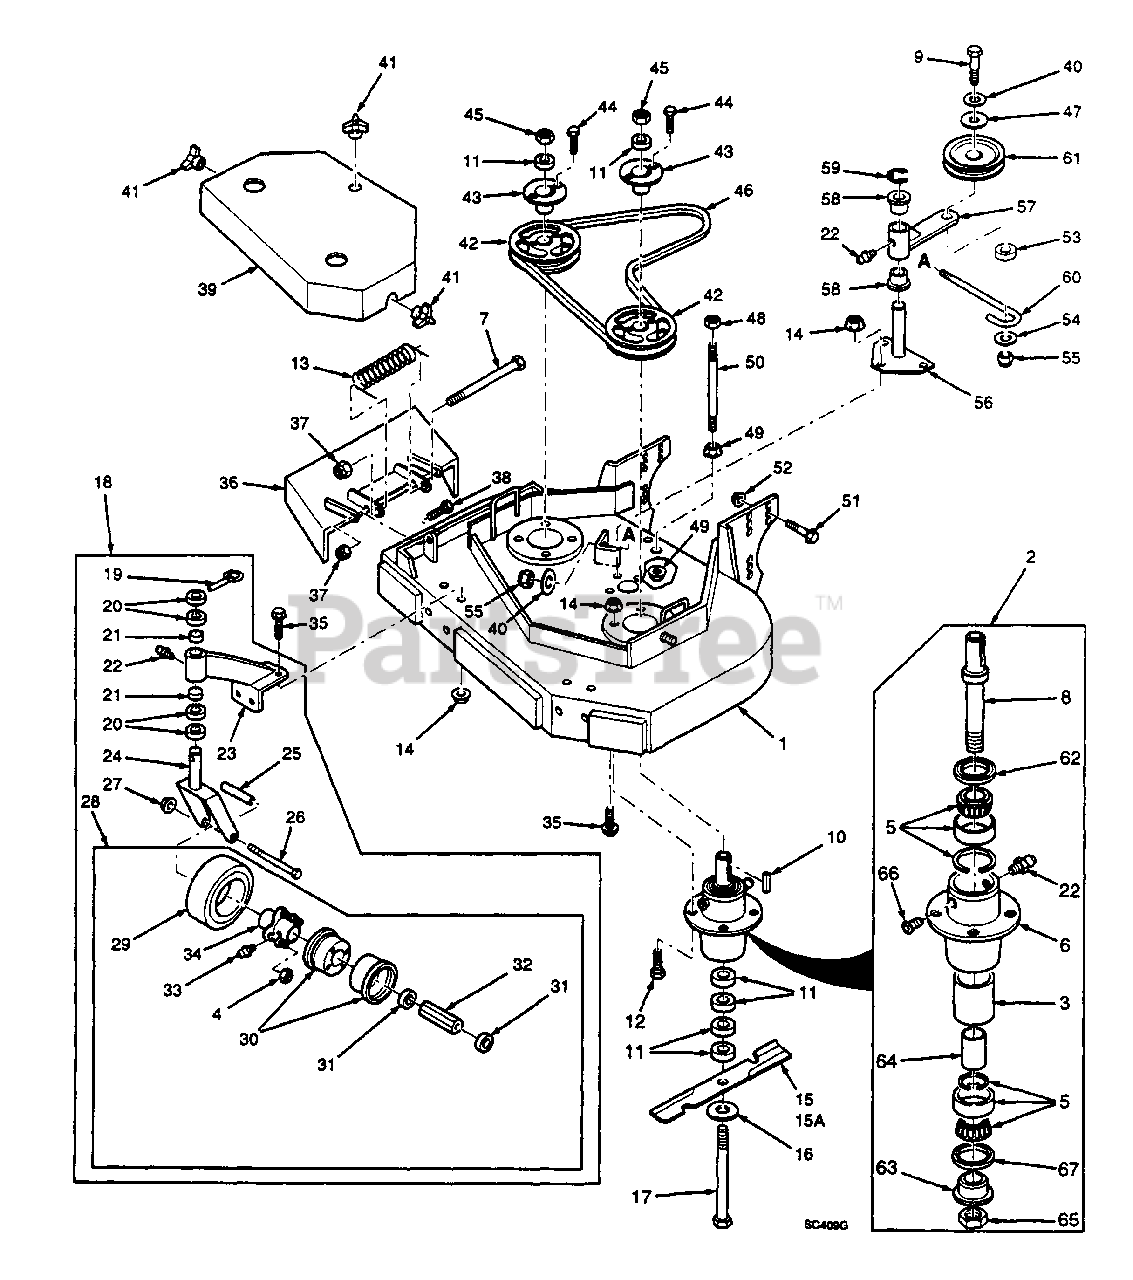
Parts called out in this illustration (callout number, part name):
1	Cutter Deck
2	Cutter Spindle Assy.
3	Spacer, Outside
4	Nut, 3/8-24 Tapered
5	Tapered Bearing, Two
6	Spindle Housing
7	Bolt,5/16-18 x 4-1/4" Hex Head
8	Spindle Shaft
9	Bolt, 3/8-16 x 3-1/2" Hex Head
10	Key, 1/4 x 1/4 x 2"
11	Spacer, Cutter Blade - Small
12	Capscrew, 5/16-18 x 1-1/4" Hex Hd
13	Spring. Cutter Deck
14	Nut 5/16-18 Serrated Flange
15	Cutter Blade 16-1/2"
15A	Cutter Blade 16-1/2 Hi Lift
16	Flatwasher, 5/8 W
17	Hex Hd. Bolt, 5/8-11 x 9-1/2"
18	Caster Assembly
19	Quick Pin
20	Spacer, Caster Yoke, 1/2" long
21	Bronze Bearing
22	Grease Fitting
23	Support Assembly
24	Caster Yoke
25	Sleeve, Caster Wheel Bearing
26	Hex Hd. Bolt, 1/2-13 x 5-1/2"
27	Elastic Stop Nut, 1/2-13
28	Wheel Assy.
29	Tire only, Caster Wheel
30	Rim Pair, Caster Wheel
31	Retainer, Bearing, Caster Wheel
32	Roller Bearing, Caster Wheel
33	Grease Fitting, 45 degree 1/4-28
34	Hub Assembly
35	Capscrew, 5/16-18 x 3/4"
36	Discharge Chute
37	Nut, 5/16-18 Elastic Stop
38	Bolt, 5/16-16 x 1 Hex Hd
39	Belt Cover Assy
40	Flat Washer, 3/8" Special
41	Wing Nut, 3/8-16
42	Pulley
43	Tapered Hub
44	Bolt, 1/4-20 x 3/4" Hex Hd.
45	Nut, 5/8-11 Hex
46	Belt, Blade Drive
47	Spacer
48	Nut, 3/8-16 Center Locknut
49	Nut, 3/8-16 Serrated Flange
50	Support, Belt Cover
51	Capscrew, 7/16-14 x 1"
52	Nut, 7/16-14
53	Spacer, J-Hook
54	Washer, 3/8 x 1-1/2 x 16 GA
55	Elastic Stop Nut, 3/8-16
56	Idler Pivot
57	Idler Arm Assy.
58	Bronze Bearing
59	Retaining Ring, 1-1/8" Ext. "E"
60	J-Hook
61	Idler Pulley, Belt Clutch
62	Seal, Cutter Spindle
63	Spindle Bushing
64	Spacer, Inside
65	Nut, Cutter Spindle
66	Relief Fitting, Cutter Spindle
67	Seal, Cutter Spindle
